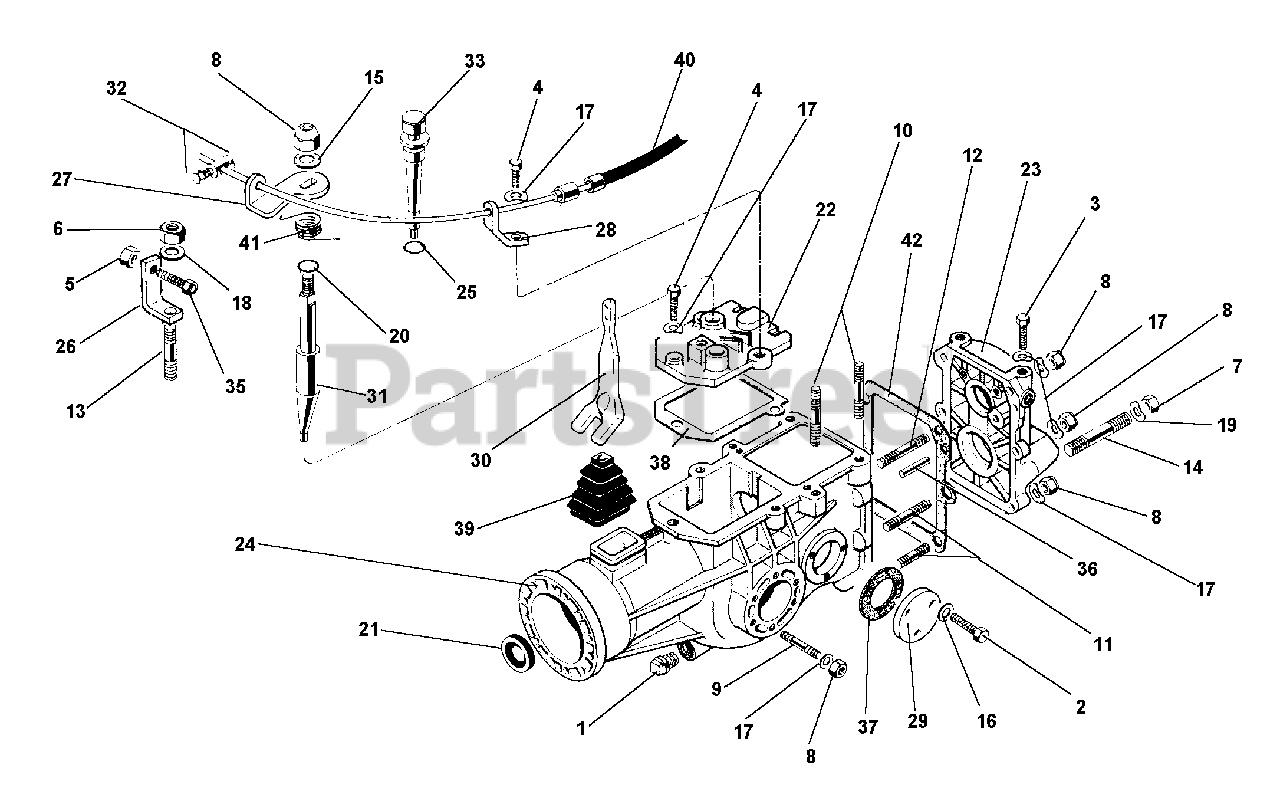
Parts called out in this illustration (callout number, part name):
1	PLUG 1/4 GAS
2	SCREW TE M6 X 10 UNI 5739 5S
3	SCREW M8 X 20
4	SCREW TE M8 X 30
7	NUT M12 X 1.25
8	NUT, SELF LOCKING M8
9	STUD M8 X 46 X 20 X 12
10	STUD M8 X 38 X 14 X 20
11	STUD M8 X 46 X 16 X 16
12	STUD M8 X 58 X 16 X 16
13	STUD M10 X 37 X 19 X 15
15	FLAT WASHER 8.4
16	WASHER, LOCK 6.4
17	WASHER, LOCK 8.4
18	WASHER, LOCK 10.5
19	WASHER, LOCK 13
20	O-RING 2056 14.00 X 1.78
22	GEARBOX COVER
25	RUBBER RING
26	BRACKET CLUTCH CONTRAST
27	LEVER RELEASE
28	CONTRAST DIFFERENTIAL SHEATH
30	CLUTCH LEVER
32	CLAMP, CABLE
33	CAP, WITH MEASURING ROD
35	SCREW, ADJUSTING M8
36	PARALLEL PIN D 6 X 20
38	GASKET, COVER
40	CABLE CLUTCH
42	COVER GASKET
